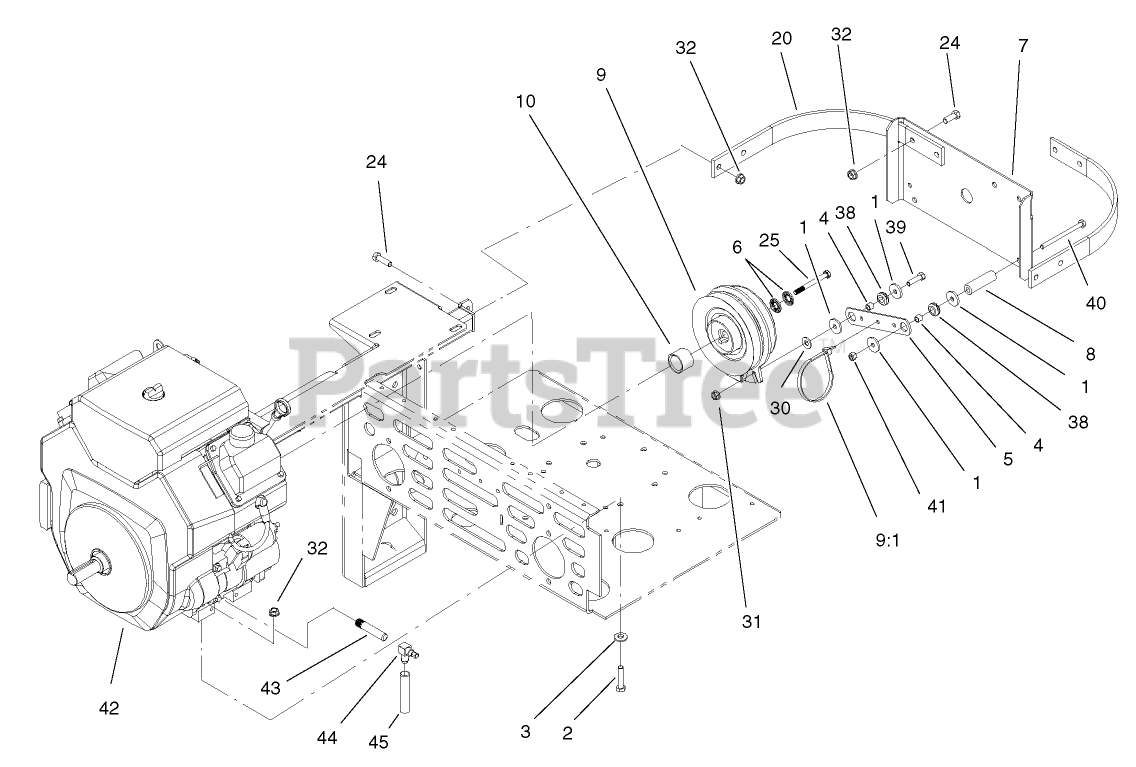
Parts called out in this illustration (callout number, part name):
1	WASHER
2	SCREW-HH
3	WASHER-BELLEVILLE
4	SPACER
5	STRAP-CLUTCH, BRAKE
6	WASHER-SPRING
7	GUARD-CLUTCH
8	SPACER-ANCHOR, CLUTCH
9	Clutch
9:1	TIE-PLASTIC
10	SPACER-CLUTCH
20	BRACKET-GUARD, TOP
24	SCREW-HH
25	SCREW-HH
30	WASHER-FLAT
31	NUT-HF
32	NUT-HHF, WHIZ
38	GROMMET
39	SCREW-HH
40	SCREW-HH
41	NUT-LOCK, NI
43	Adapter
44	Valve-Drain, Oil
45	HOSE-DRAIN, OIL
